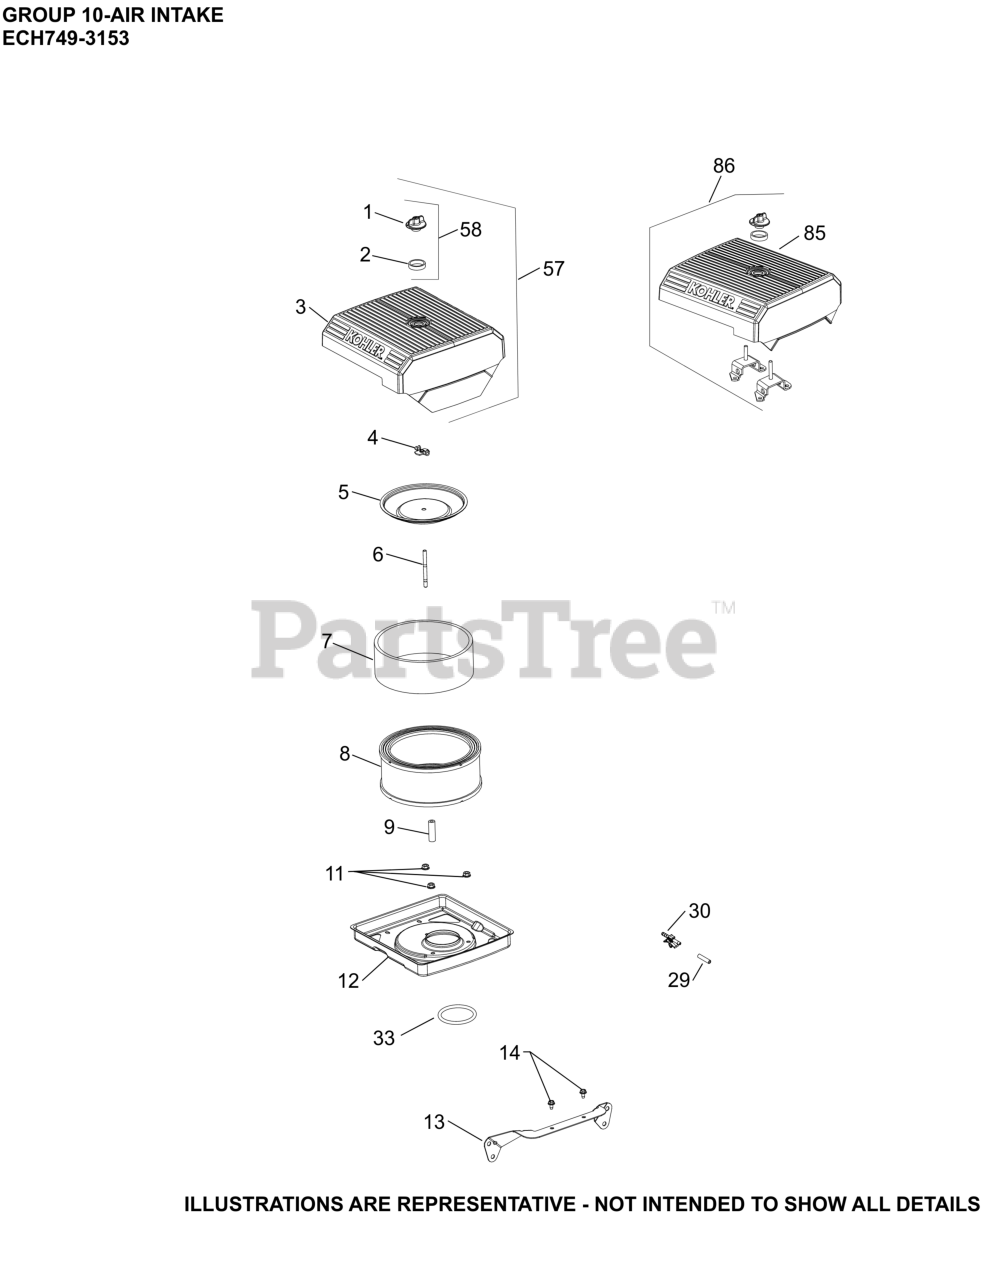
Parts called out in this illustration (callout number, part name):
1	KNOB, COVER
3	COVER, AIR CLEANER
4	NUT, WING
5	COVER, INNER AIR CLEANER
6	STUD, LOW PROFILE A/C
7	PRE-CLEANER (HIGH)
8	AIR FILTER ELEMENT
11	NUT, FLG M6X1.0
12	BASE, AIR CLEANER
13	AIR CLEANER BRACKET
14	SCREW, THREAD FORMING
29	CAP, MASKING
30	CONNECTOR, EVAPORATIVE
33	O-RING, AIR CLEANER BASE
57	KIT, AIR CLEANER COVER
58	KIT, KNOB W/SEAL
85	COVER, AIR CLEANER
86	KIT, AIR CLEANER COVER
